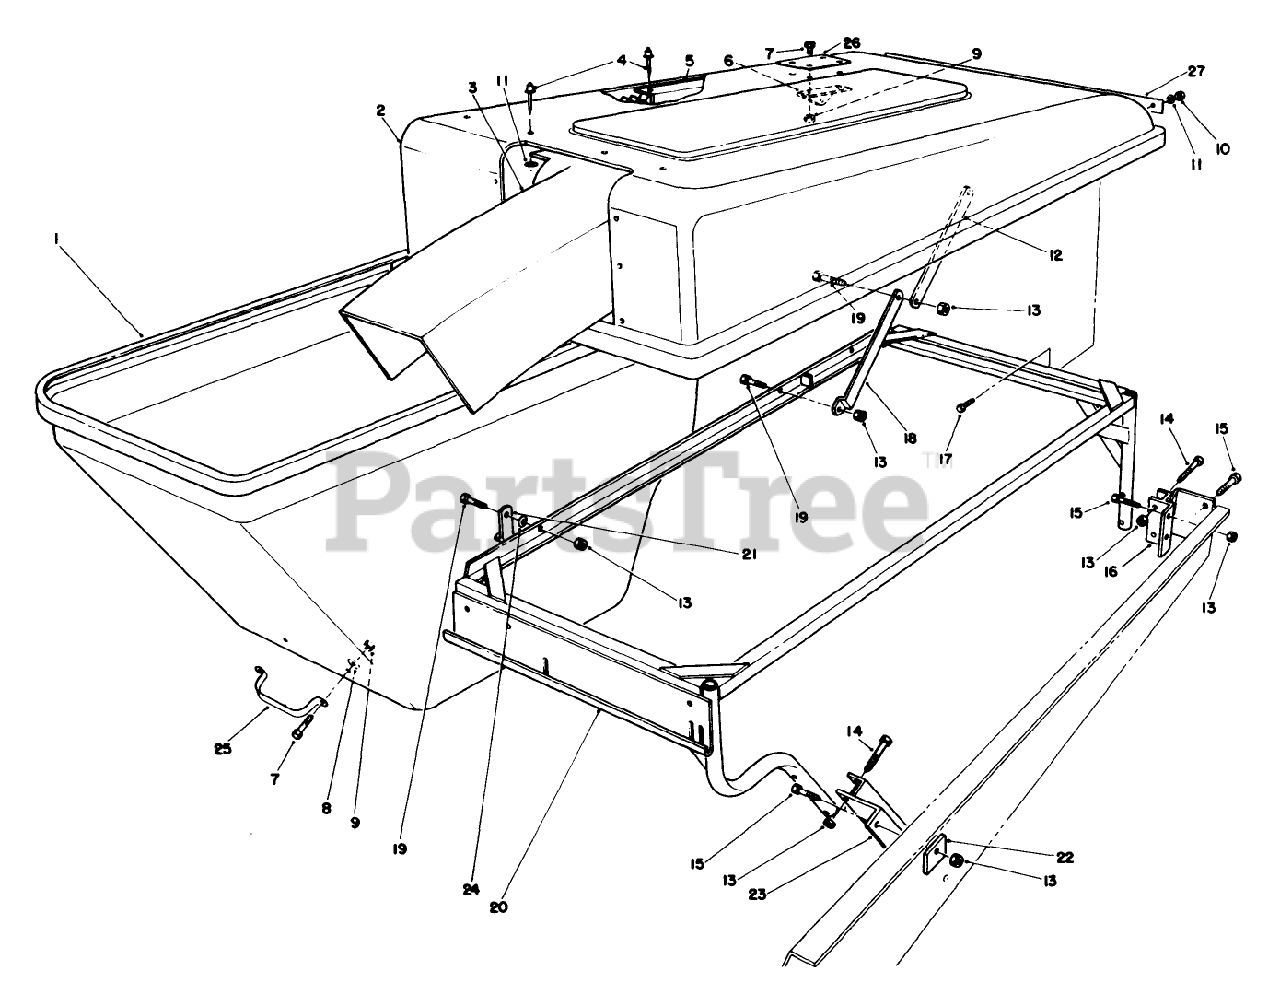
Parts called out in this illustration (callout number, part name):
2	BAGGER HOOD
3	BAGGER SNOUT
4	RIVET-POP
7	SCREW-HH
8	WASHER-FLAT
9	NUT-LOCK, NI
10	NUT-LOCK, NI
11	WASHER-FLAT
13	NUT-LOCK, NI
14	SCREW-HH
15	SCREW-HH
19	SCREW-HH
20	HOPPER FRAME WA
24	WASHER-SPRING
25	Handle
27	HINGE PLATE
